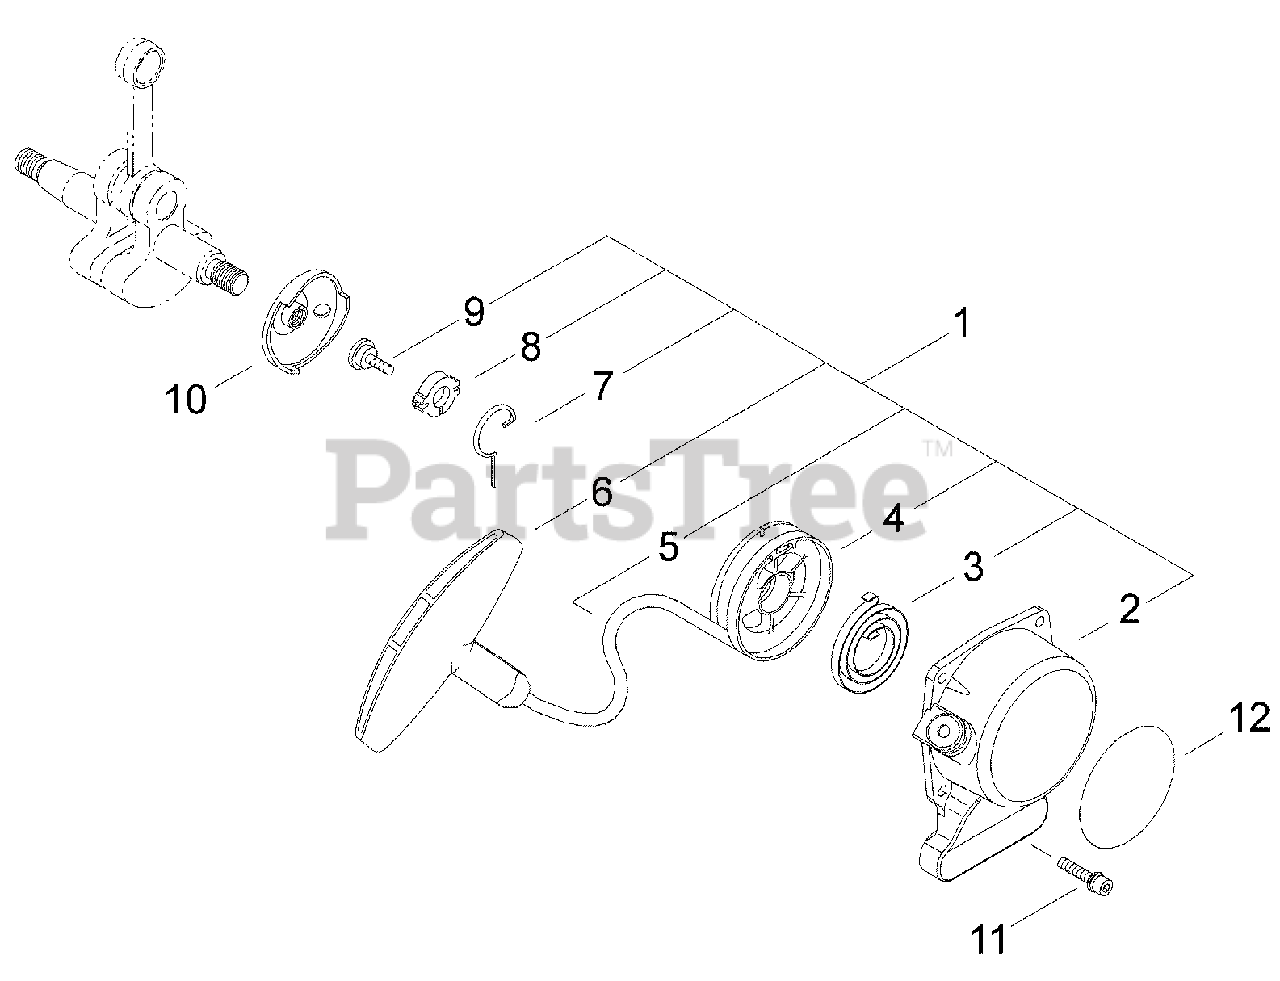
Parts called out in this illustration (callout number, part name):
1	STARTER ASSY
2	CASE, STARTER
3	SPRING, REWIND
4	REEL, ROPE
5	ROPE, STARTER
6	GRIP, STARTER
7	PAWL, STARTER
8	WASHER - 5
9	SCREW - 5
10	STARTER PAWL ASSY
11	SCREW - 4X14
12	LABEL - E4
